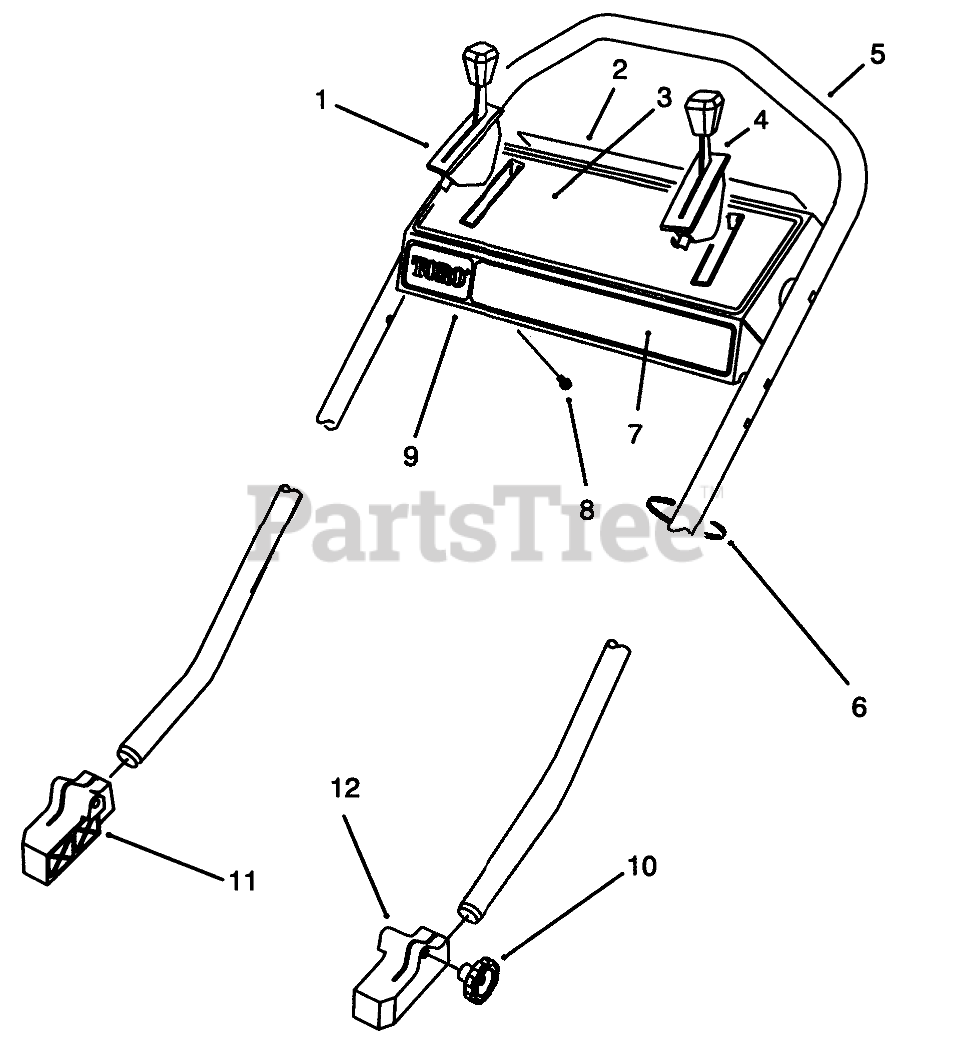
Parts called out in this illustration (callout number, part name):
1	GROUND SPEED CONTROL
2	DECAL - PANEL, REAR
3	DECAL-INSTRUCTION BBC
4	THROTTLE CONTROL
5	HANDLE PVC DIP
6	TIE-CABLE
7	DECAL - PANEL BBC
8	SCREW-HWHTF
9	Control Panel Assembly (Incl. Ref. #2, 3, & 7)
11	MOUNT-HANDLE, RH
12	MOUNT-HANDLE, LH
